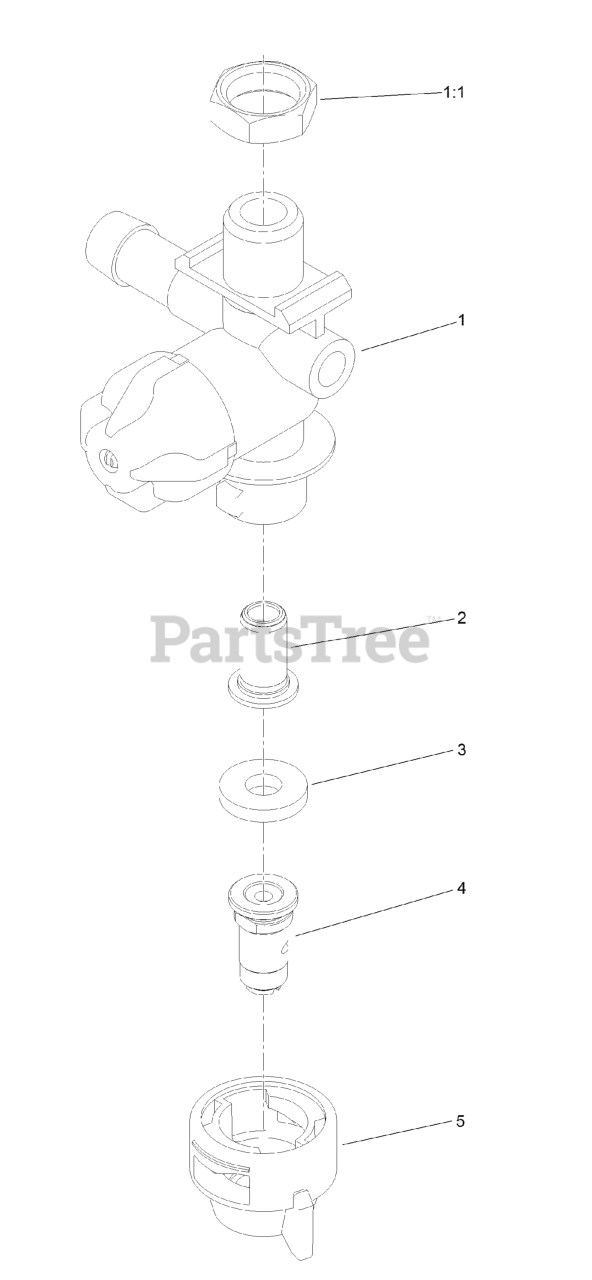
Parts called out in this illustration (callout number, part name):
1	RH NOZZLE BODY ASM
1:1	NUT-NYLON
2	STRAINER-TIP
4	NOZZLE-SPRAY, WHITE
5	CAP-NOZZLE
